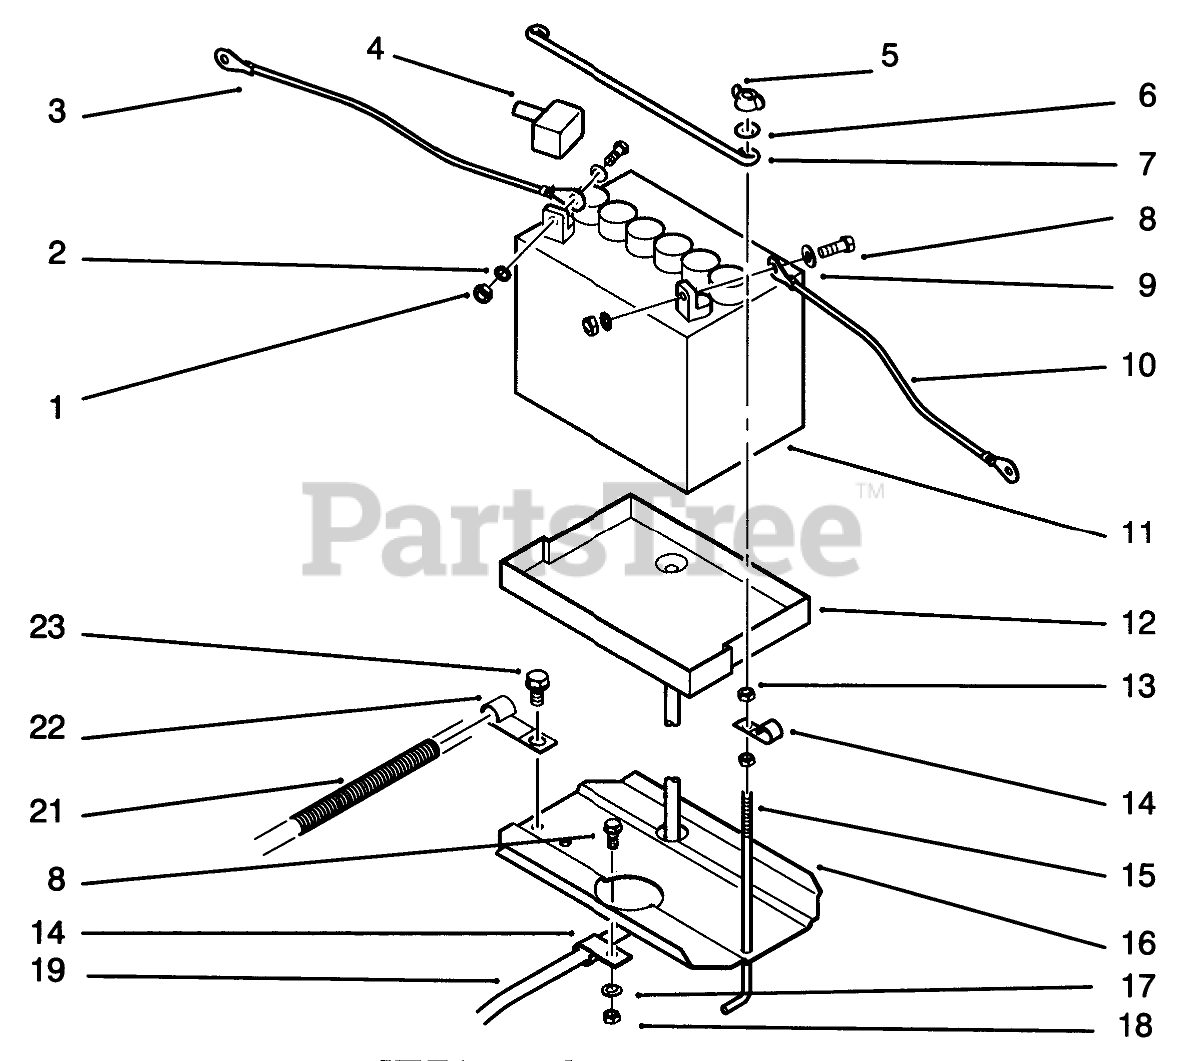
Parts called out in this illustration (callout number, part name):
1	NUT-HEX
2	Washer
3	ASS'Y-WIRE
4	Boot
5	NUT-WING
6	WASHER-FLAT
7	ROD-BATTERY HOLD DWN
8	SCREW-HH
9	WASHER-FLAT
10	WIRE -BLACK
11	Battery
12	TRAY-BATTERY
13	Nut
14	CLAMP
16	Tray
17	WASHER-FLAT
18	NUT-LOCK, NI
19	TUBE-21" BATTERY DRAIN
21	WIRING-HARNESS
22	CLIP
23	Screw
